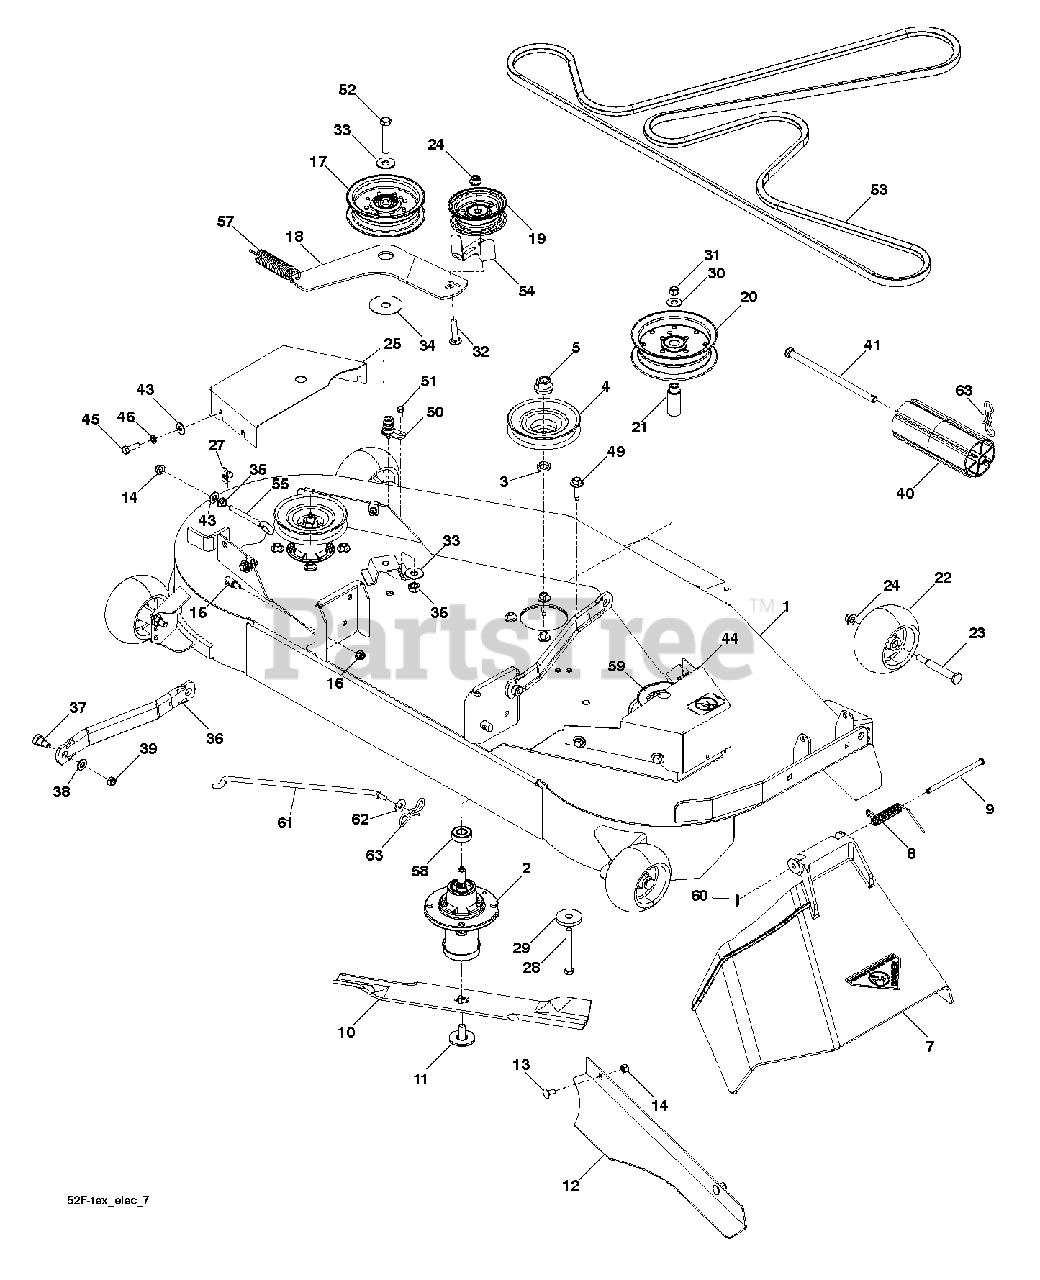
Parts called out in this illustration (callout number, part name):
1	DECK SVCX.52F.498
2	MANDREL.DECK.ASSEMBLY
3	WASHER.SPACER.MANDREL
4	PULLEY.DRIVEN.DECK.48'
5	NUT.FLANGE.LOCK.TOP
7	DISCHARGE CHUTE 52"
8	SPRING - TORSION
9	PIN-CLEVIS 5/16 DIA X 5.19 ZD
10	BLADE, 17.75 X 2.5 X .25
11	BOLT.WASHER.ASM.7/16-2
12	PLATE.52".CONFINEMENT.BLACK
13	BOLT
14	NUT.71038.31-18.HEX.NYLOCK
15	STUD.FASTNER.W/ANTI-ROTATE
16	NUT LOCK FLG 3/8-16 UNC
17	PULLEY.IDLER.MWR.STATI.LH
18	ARM, IDLER, 52" BLK
19	PULLEY.IDLER.FLAT
20	PULLEY, IDLER
21	BUSHING, IDLER
22	WHEEL GAGE DONUT
23	BOLT.SHOULDER.3/8-16X3-5/8.
24	NUT 3/8-16 HEX FLG NYLOC ZD
25	SHIELD.BELT.LH.52.PNT.498
27	U-CLIP 5/16-18 NUT RETAINER
28	HCS 3/8-16 X 3-1/2 GR5 ZD
29	SPINDLE WASHER
30	WASHER 3/8 FLAT
31	NUT 3/8-16 NYLOC
32	RHSNB 3/8-16X1-3/4
33	WASHER 7/16 FLAT ZD
35	NUT.LOCK.FLANGE.7/16
36	ARM.SUSPENSION.MOWER
37	SB 3/8-16 X 3/8 SKT HD ZD
38	WASHER
39	NUT HEX 3/8-16 NYLON, THIN
40	NOSE ROLLER 48"
41	ROD.ROLLER.NOSE.NARROW.48"
43	WASHER
44	SHIELD.BELT.RH.52.PNT.498
45	BOLT.FIN.HEX.5/16-18UNC X 1.00
46	WASH.5/16.SLW.ZD
49	BOLT.HEX.WASHR.HED.313-18X1.19
50	PORT.WASHOUT
51	SCREW
52	BOLT.HEX.7/16-14
53	BELT, 143.5" EL
54	GUARD, BELT
55	EYE BOLT 5/16 X 3.50
59	RP PULLEY, COLLECTION 48
60	RETAINER CLIP
61	ROD.ANTI.SWAY.48/54"TE
62	WASHER
63	PIN.COTTER.5/16.BOW TI
